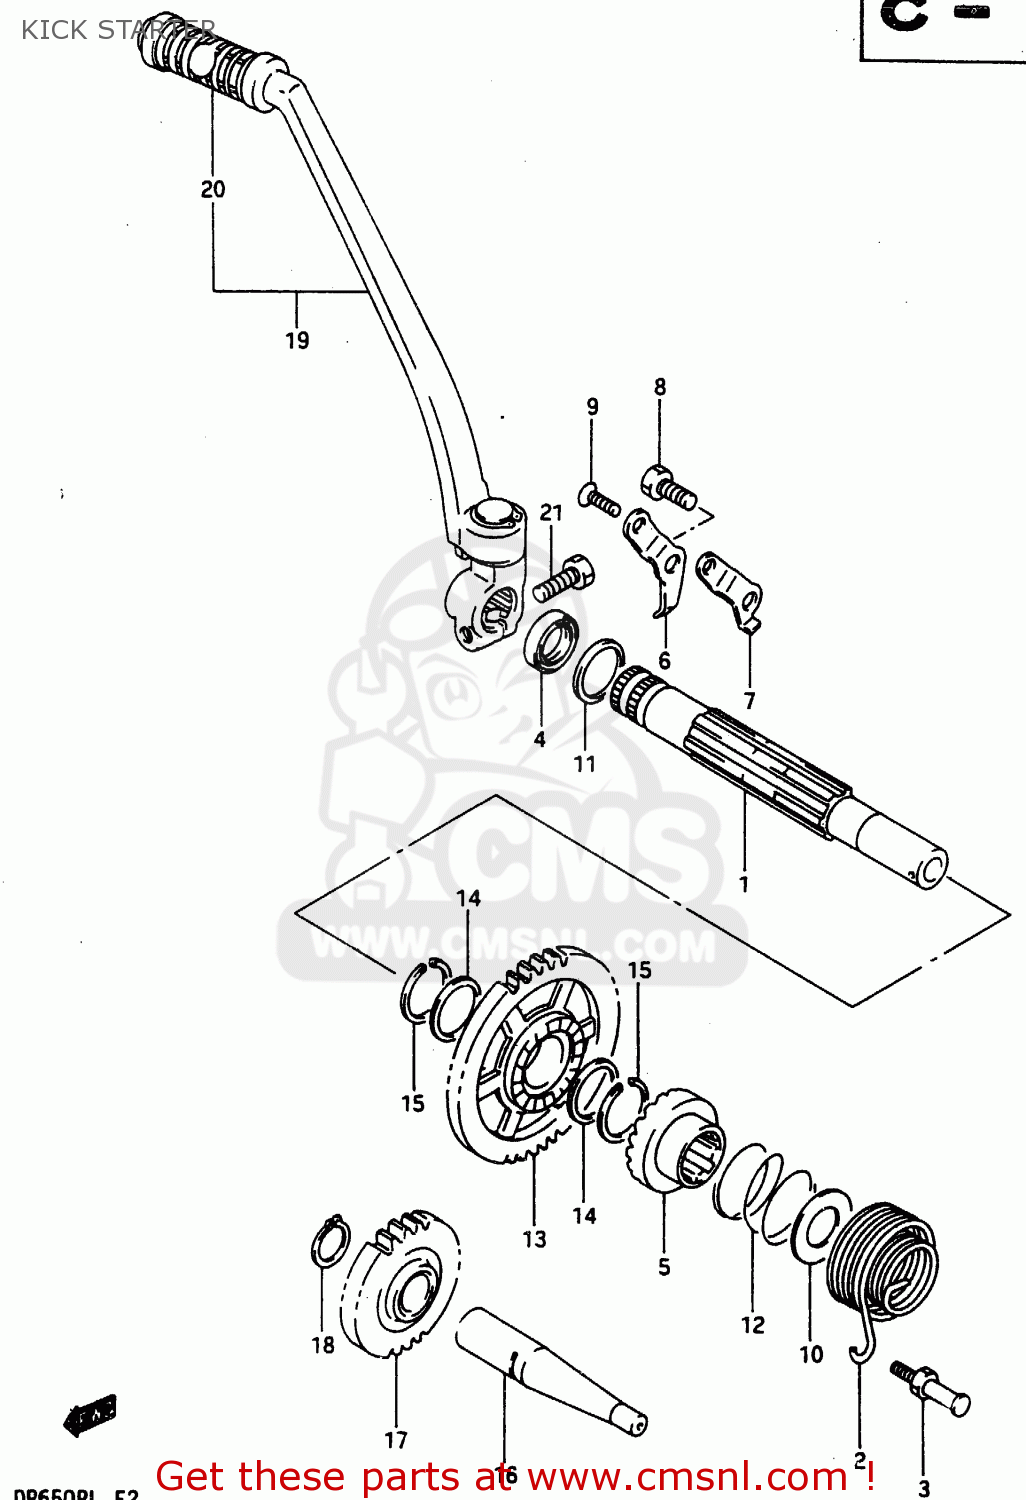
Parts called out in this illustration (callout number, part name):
1	SHAFT,KICK STARTER
2	SPRING
3	BOLT,KICK SHAFT SPRING
4	SEAL,OIL(20X27X6)
5	STARTER,KICK
6	GUIDE,KICK STARTER
7	STOPPER,KICK STARTER
8	BOLT,8X1.25X2
9	SCREW
10	WASHER
11	WASHER,THRUST
12	SPRING
13	GEAR,KICK STARTER DRIVE
14	SHIM
15	CIRCLIP
16	SHAFT,KICK STARTER IDLE
17	GEAR,KICK STARTER IDLE
18	CIRCLIP
19	LEVER ASSEMBLY,KICK STARTER
20	RUBBER,KICK STARTER PEDAL
21	BOLT 8X25
